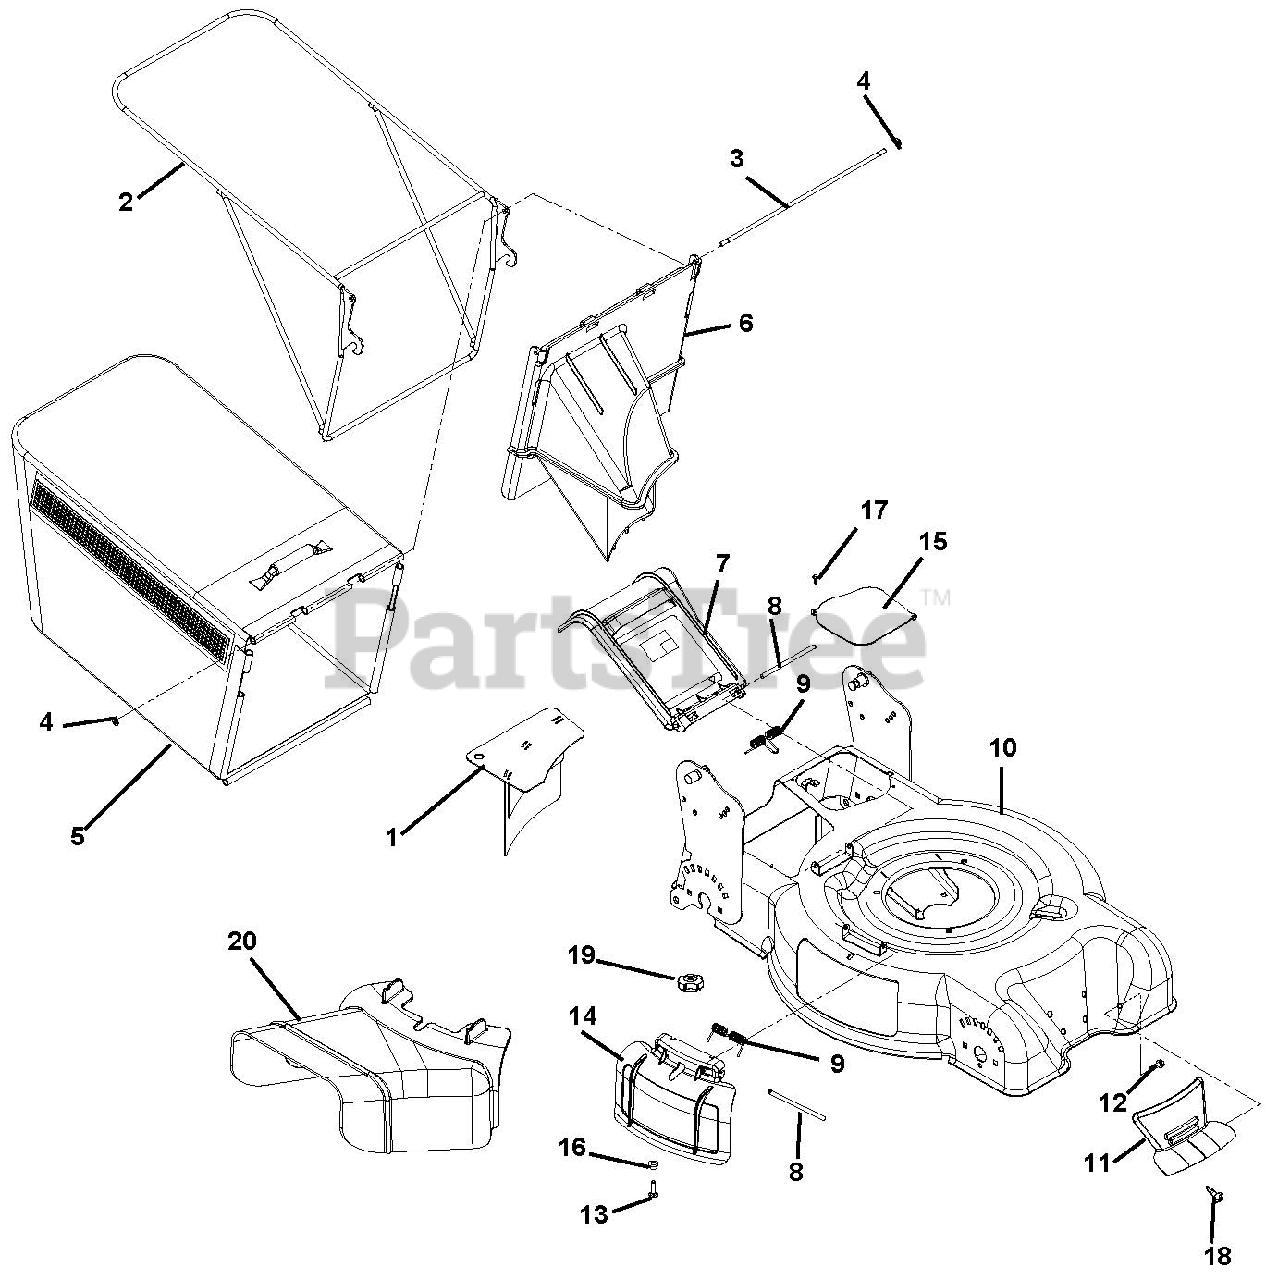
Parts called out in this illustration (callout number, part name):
1	PLUG, MULCH (STEEL)
2	BAGGER FRAME
3	ROD, HINGE
4	NUT-PUSH .25X.50 O.D.
5	WBLM, ARIENS BAGGER
6	BAGGER DOOR
7	REAR DISCHARGE COVER
8	PIN, HINGE
9	TORSION SPRING
10	21" DECK WELDMENT
11	GRILL INSERT
12	SCR-TAP 12-12X.75 HI-LOW YZ
13	@BLT-RDHDSQNK .25-20X.75 G5YZ
14	MULCH COVER
15	COVER, TRANSMISSION ACCESS
16	NUT-PUSH .25X.50 O.D.
17	@SCR-TAP 10-24X.375 HWH YZ TR
18	SCREW, SELF DRILL/TAP
19	KNOB-CLAMPING, .250-20 NYLOC
20	DISCHARGE CHUTE
